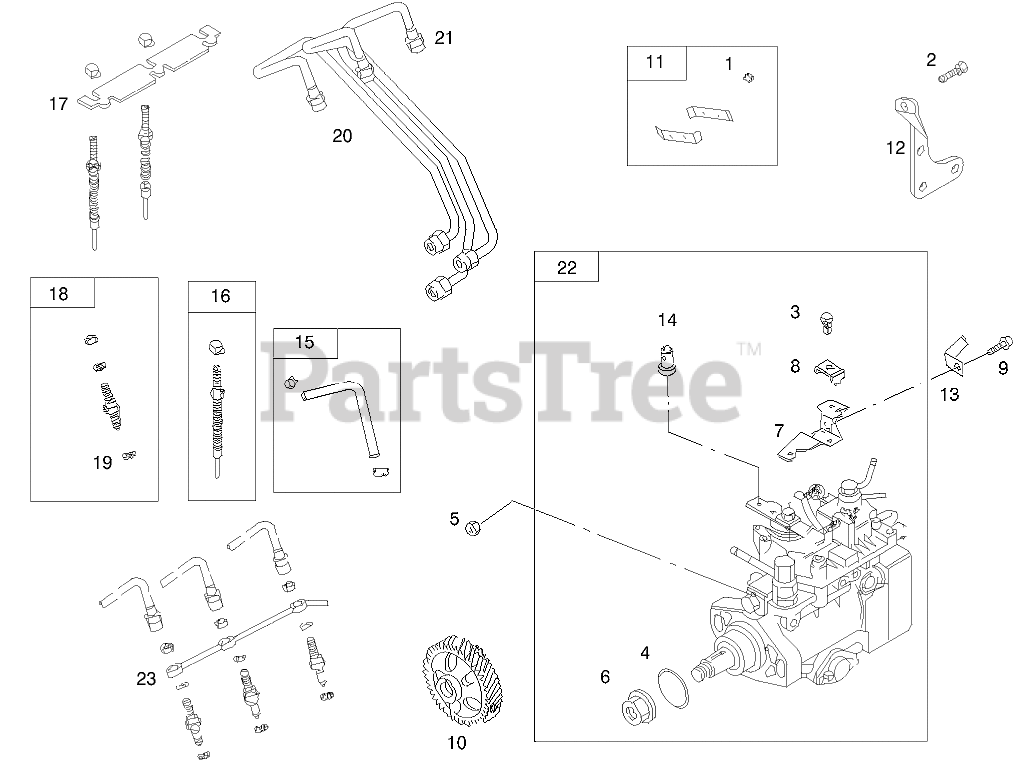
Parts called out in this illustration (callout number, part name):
1	SCREW-HEX
2	SCREW-HEX
3	SCREW-HEX
4	O-RING
4	NIPPLE ASM
5	NUT-HEX, METRIC
5	VALVE ASM
6	NUT-HEX, METRIC
7	BRACKET-CLAMP, CASING
8	CLAMP-CASING
9	SCREW-HEX
9	GASKET-SET
10	GEAR-DRIVE
11	CLAMP
12	BRACKET-SUPPORT
13	Bracket-Support
14	CLAMP-SWIVEL
14	VALVE OVERHAUL KIT
15	HOSE / CLAMP ASM
15	SHAFT-GEAR
16	PLUG-GLOW
17	STRAP-PLUG, GLOW
18	NOZZLE-INJECTOR
19	SEAT-INJECTOR
20	PIPE-INJECTOR, NO. 2
21	PIPE-INJECTOR, NO. 3
22	PUMP-INJECTION
23	PIPE-RETURN, FUEL
